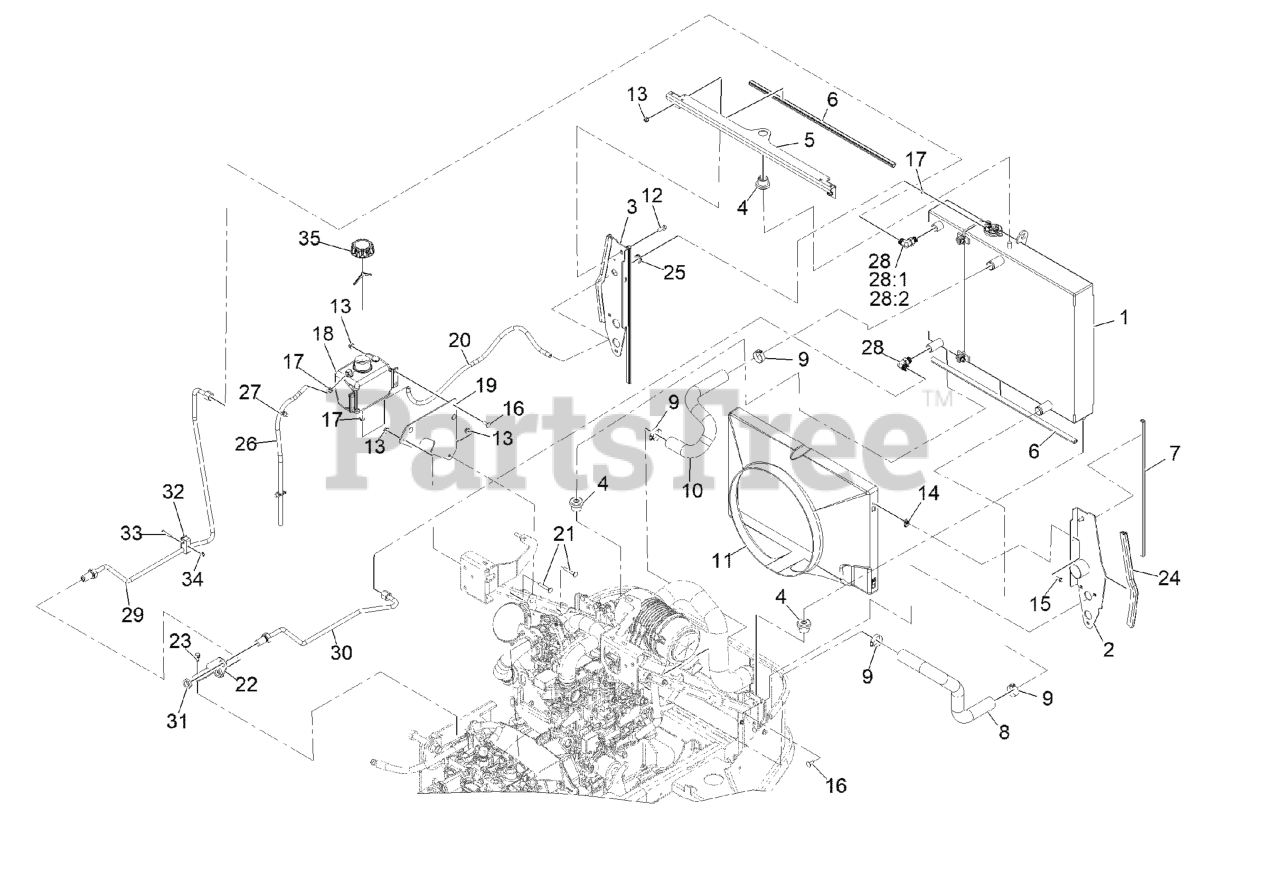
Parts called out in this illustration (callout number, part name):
1	COOLING ASM
2	SUPPORT-RADIATOR, LH
3	SUPPORT-RADIATOR, RH
4	MOUNT-ISOLATOR
5	BRACKET-COOLING, TOP
6	SEAL-BULB
7	SEAL-BULB
8	HOSE-RADIATOR, LOWER
9	CLAMP-HOSE
10	HOSE-RADIATOR, UPPER
11	SHROUD-FAN
12	SCREW-HHF
13	NUT-HF, NI
15	SCREW-HWH
16	SCREW-CARR
17	CLAMP-HOSE
18	TANK-OVERFLOW, W/CAP
19	BRACKET-BOTTLE
20	HOSE-FUEL
21	BOLT-CARR
22	BRACKET-BULKHEAD
23	Screw-HWH 5/16-18 X 3/4 Tf
24	SEAL-BULB
25	GROMMET
26	HOSE-FUEL
27	CLIP-TIE
28	FITTING-ELBOW, 90 DEG
28:1	O-RING
28:2	O-RING
29	HYDRAULIC TUBE ASM
30	HYDRAULIC TUBE ASM
31	NUT-BULKHEAD
32	CLAMP-TWIN
33	SCREW-HH
35	CAP-W/TETHER
